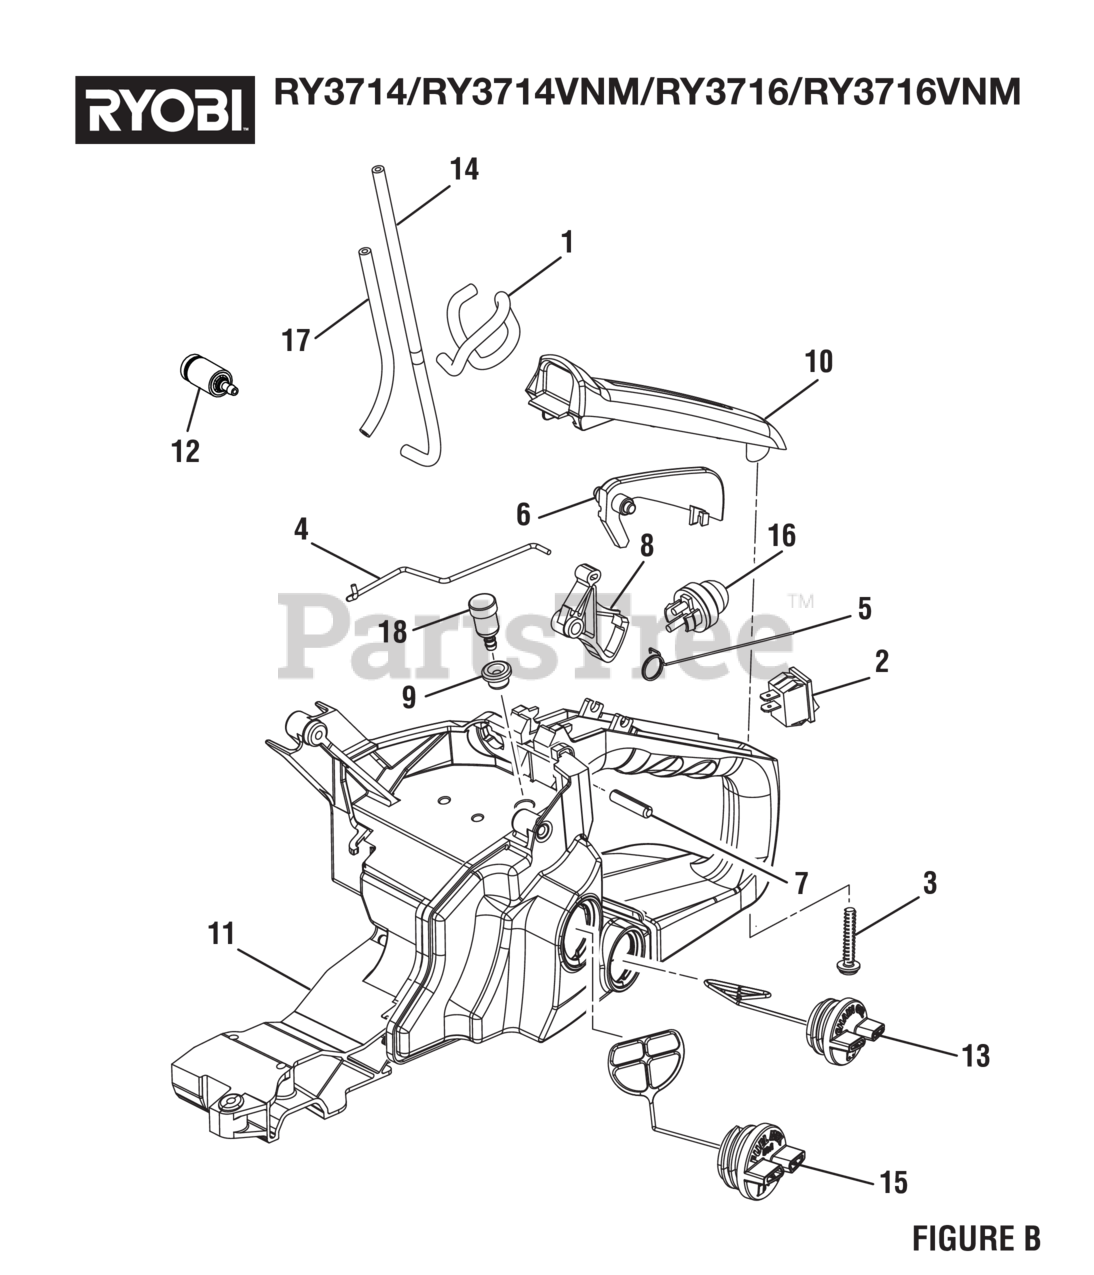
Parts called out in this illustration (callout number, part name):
1	Fuel Hose (Primer Assembly to Carburetor, 160 mm)
3	Screw (M5 x 27 mm, T25 Torx Pan Hd.)
4	Throttle Rod.
5	Throttle Spring
6	Safety Rock Arm
7	Spring Pin
8	Throttle Trigger
10	Grip Cover
11	Rear Handle Assembly
12	Fuel Filter Assembly
13	Oil Cap Assembly
14	LP-1500 Tubing (205.00 mm)
15	Fuel Cap Assembly
16	Primer Bulb
17	Fuel Hose (Primer Assembly to Tank, 153 mm)
18	Fuel Breather Assembly
